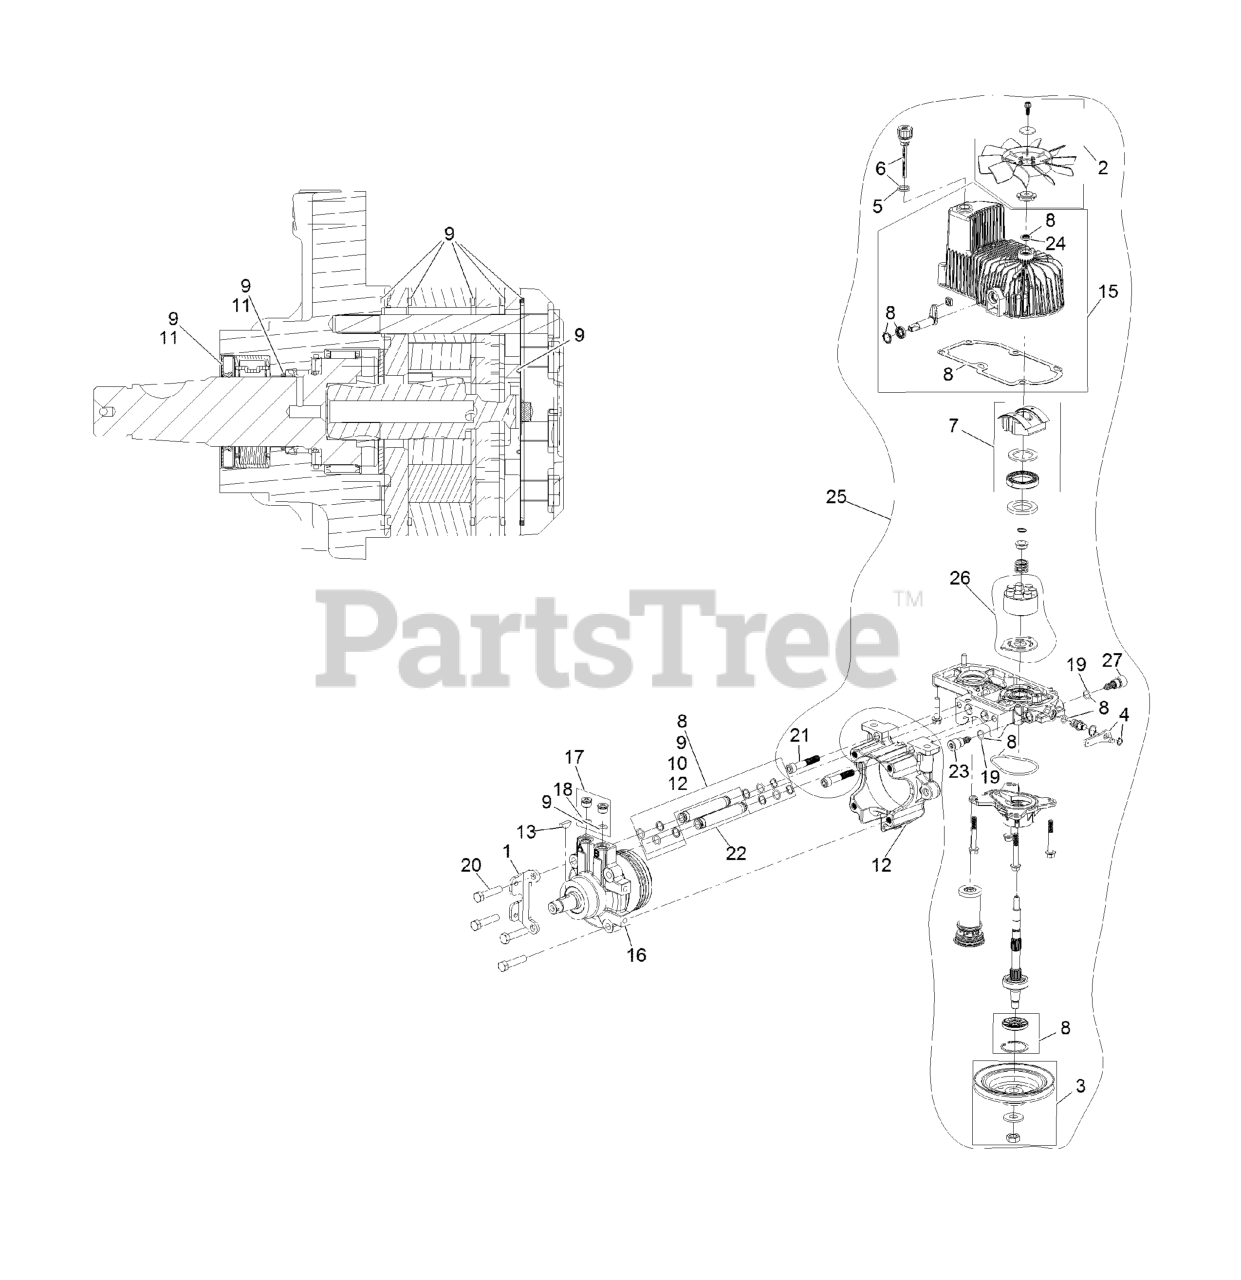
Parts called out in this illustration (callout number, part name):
1	Plate, Horse Shoe Mount
2	Kit, 7.8 In Fan
3	PULLEY KIT
4	HANDLE-BYPASS VALVE, HYDRO
5	DIPSTICK-HYDRO W/GASKET
6	GASKET-DIPSTICK, HYDRO
7	SWASH BLOCK KIT
8	Kit, Pump Seal
9	MOTOR SEAL KIT
10	TUBE SEAL KIT
11	OUTPUT SHAFT SEAL KIT
12	NOSE CUP-UHT
13	KEY-WOODRUFF
15	Kit, Housing-Hydro RH
16	KIT, MOTOR TG310CC RH
17	MAGNETIC PLUGS SERVICE KIT
19	O-RING-CHECK VALVE
20	SCREW HH
21	SCREW-HSH
22	HYDRAULIC TUBE KIT
23	SHOCK VALVE, 12CC HYDRO
24	SEAL-FAN DRIVE
25	Kit, Pump Section 16Cc RH
26	Kit - 16Cc Port Plate,Rotate Grp
27	Shock Valve Orificed 3800
